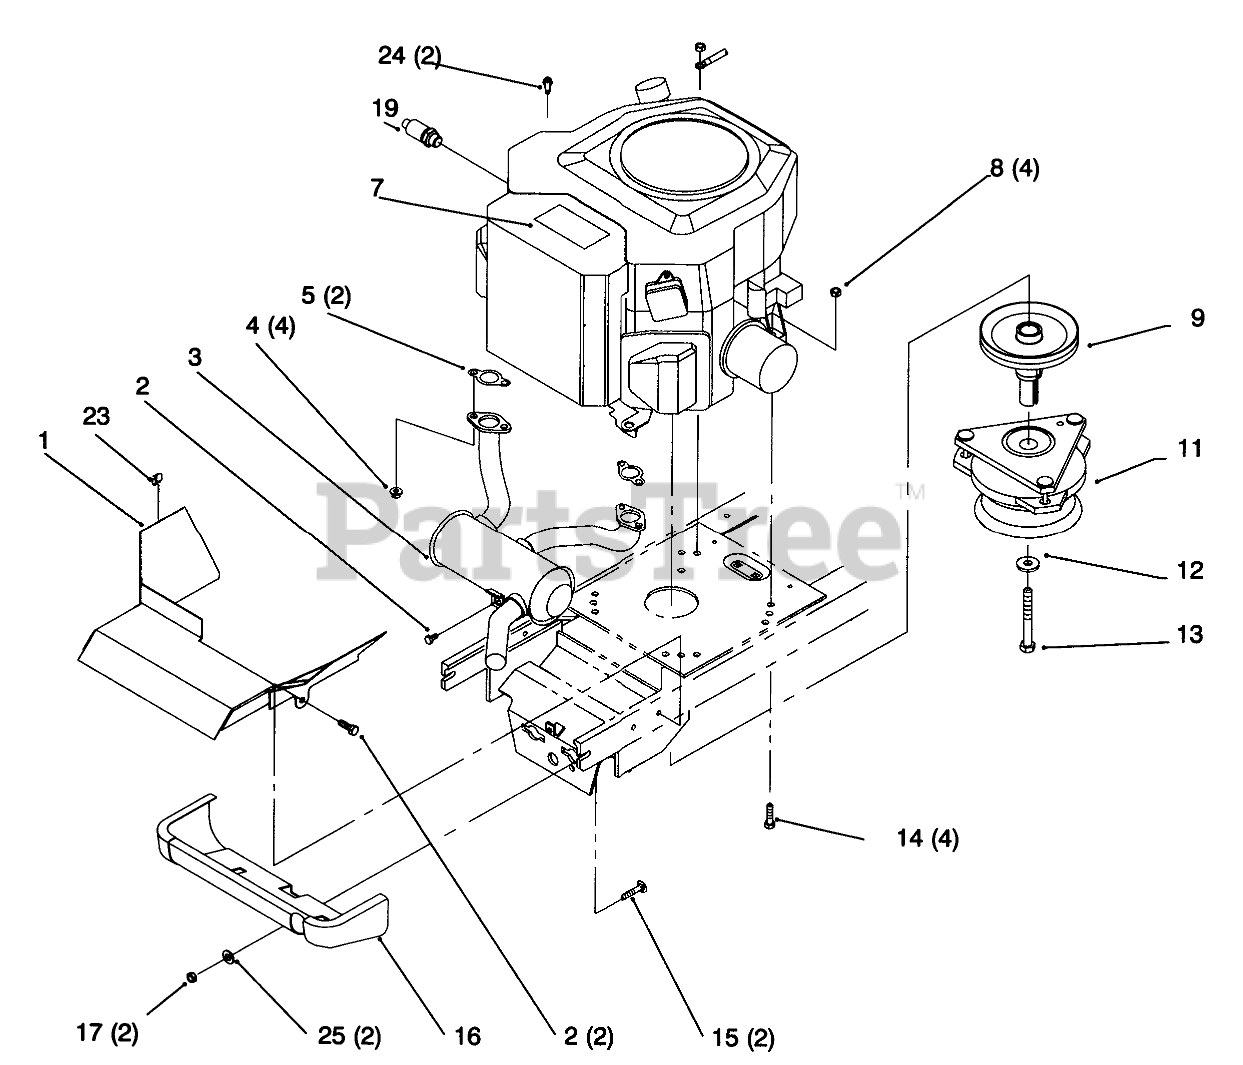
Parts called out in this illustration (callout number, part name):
1	Baffle-Muffler (Only On: 72103)
2	Screw-HWHTF (Only On On: 72103)
3	Muffler (Only On: 72103)
4	Nut-HHF (Only On: 72103)
5	Gasket-Exhaust (Only On: 72103)
7	Decal-Toro Power Plus 18 (Only On: 72103)
8	Nut-Lock (Only On: 72103)
9	Pulley (Only On: 72103)
11	Clutch-PTO (Only On: 72103)
12	Washer-PTO (Only On: 72103)
13	Screw HH (Only On: 72103)
14	Screw-HH (Only On: 72103)
15	Bolt-CARR (Only On: 72103)
16	Shield-Muffler (Only On: 72103)
17	Nut-Lock (Only On: 72103)
19	Valve-Oil Drain (Only On: 72103)
23	Clip-Wire Retainer (Only On: 72103)
24	Screw-PPH (Only On: 72103)
25	Washer-Flat (Only On: 72103)
